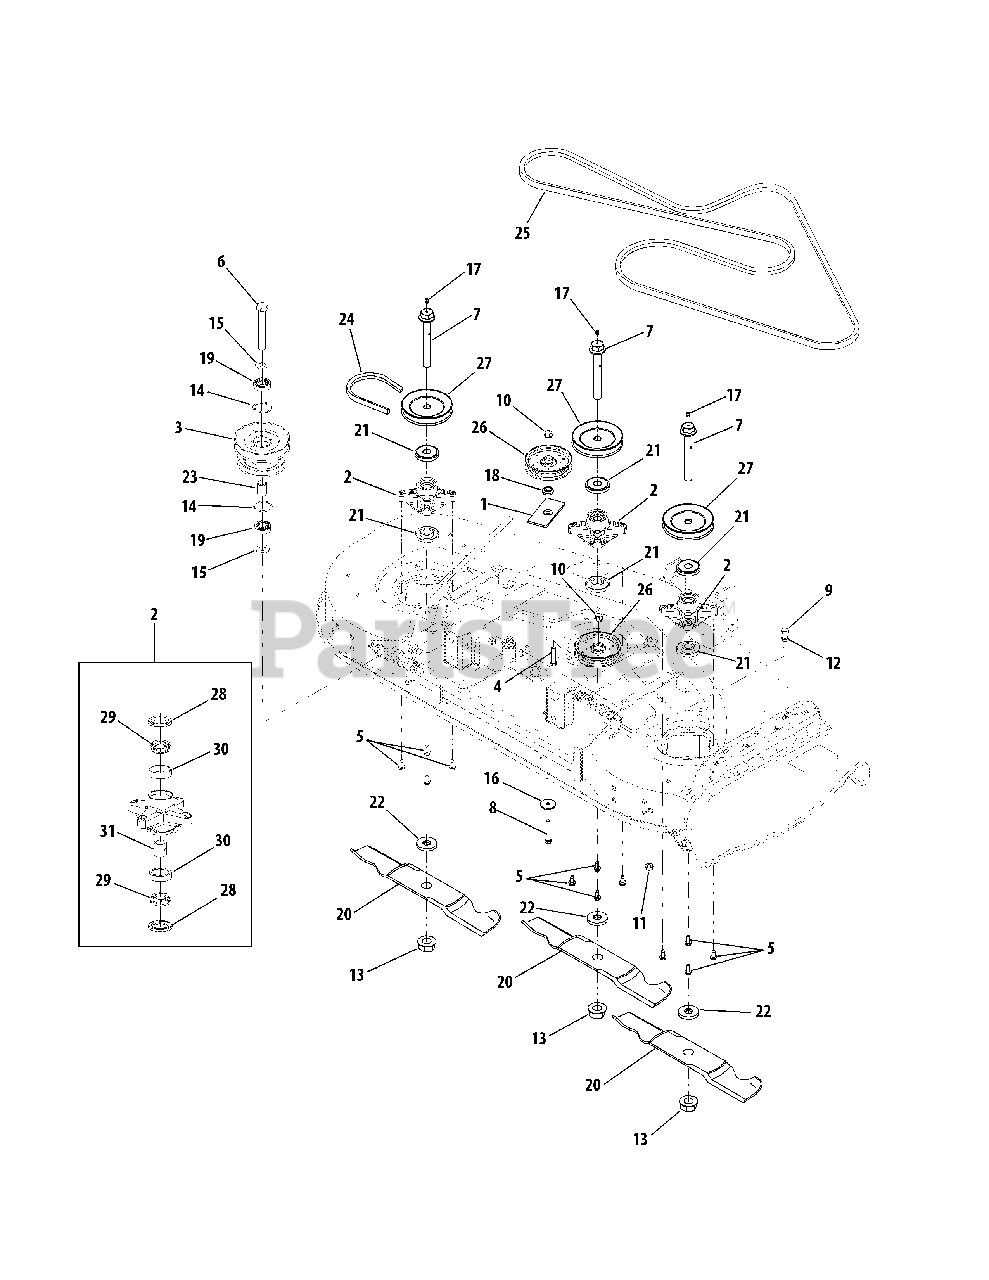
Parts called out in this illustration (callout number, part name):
1	Assembly, Spacer
2	Assembly, Spindle Includes Ref. Nos. 28 thru 31
3	Pulley, Double
4	Screw, Hex Cap, 3/8-16 x 1.75 GR5
5	Screw, Hex Wash Hd Tapp, 5/16-18 x 1.0
6	Screw, Hex Cap, 5/8-18 x 3 GR5
7	Bolt, Spindle, 3/4-16 x 5.215
8	Screw, Hex Cap, 3/8-16 x 2.75GR8
9	Screw, Hex Cap, 5/16-18 x 2.25 GR5
10	Nut, Flange Lock 3/8-16 GRF
11	Nut, Flange Lock, 5/16-18 GR5
12	Nut, Hex, 5/16-18 GR5
13	Nut, Hex Flange, 3/4-16
14	Ring, Internal Retaining
15	Washer, Flat .65 x 1.25 x .075
16	Washer, Flat .406 x 1.5 x .105
17	Fitting, Grease
18	Spacer, Shoulder
19	Bearing, Ball,
20	Blade, High Lift 18.5" Lg.
21	Spacer, Deck Spindle
22	Spacer, Blade
23	Spacer, .635 x .88 x 1.25
24	Belt, "V" 114.24" Lg.
25	Belt, "V" 111.4" Lg.
26	Pulley, Flat, 4.25 Dia.
27	Pulley, "V"
28	Seal, Oil, 1.25 x 1.874 x .25
29	Bearing, Cone
30	Cup, Bearing
31	Spacer, Bearing
